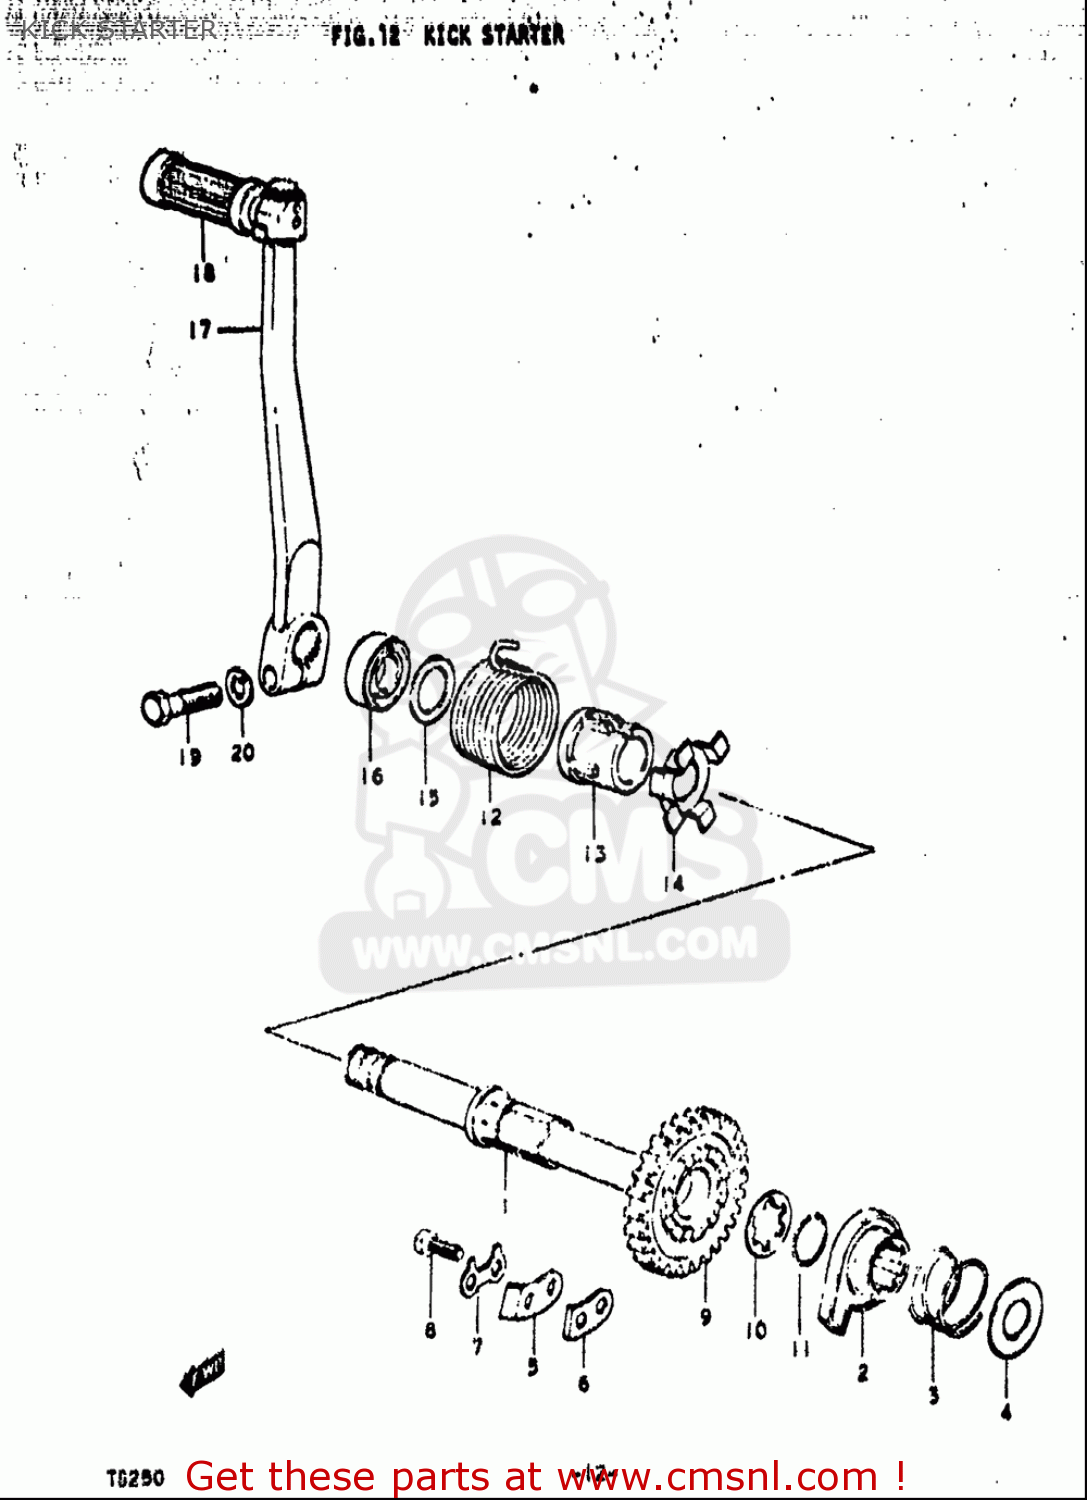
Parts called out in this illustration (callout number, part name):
2	STARTER,KICK
3	SPRING
4	WASHER
5	GUIDE,KICK STARTER
7	WASHER
8	BOLT
10	WASHER,LOCK
11	CIRCLIP
12	SPRING
14	HOLDER,KICK SHAFT SPRING
15	WASHER
16	SEAL,OIL(20X37X7)
18	RUBBER,KICK STARTER PEDAL
19	BOLT
20	WASHER,LOCK
